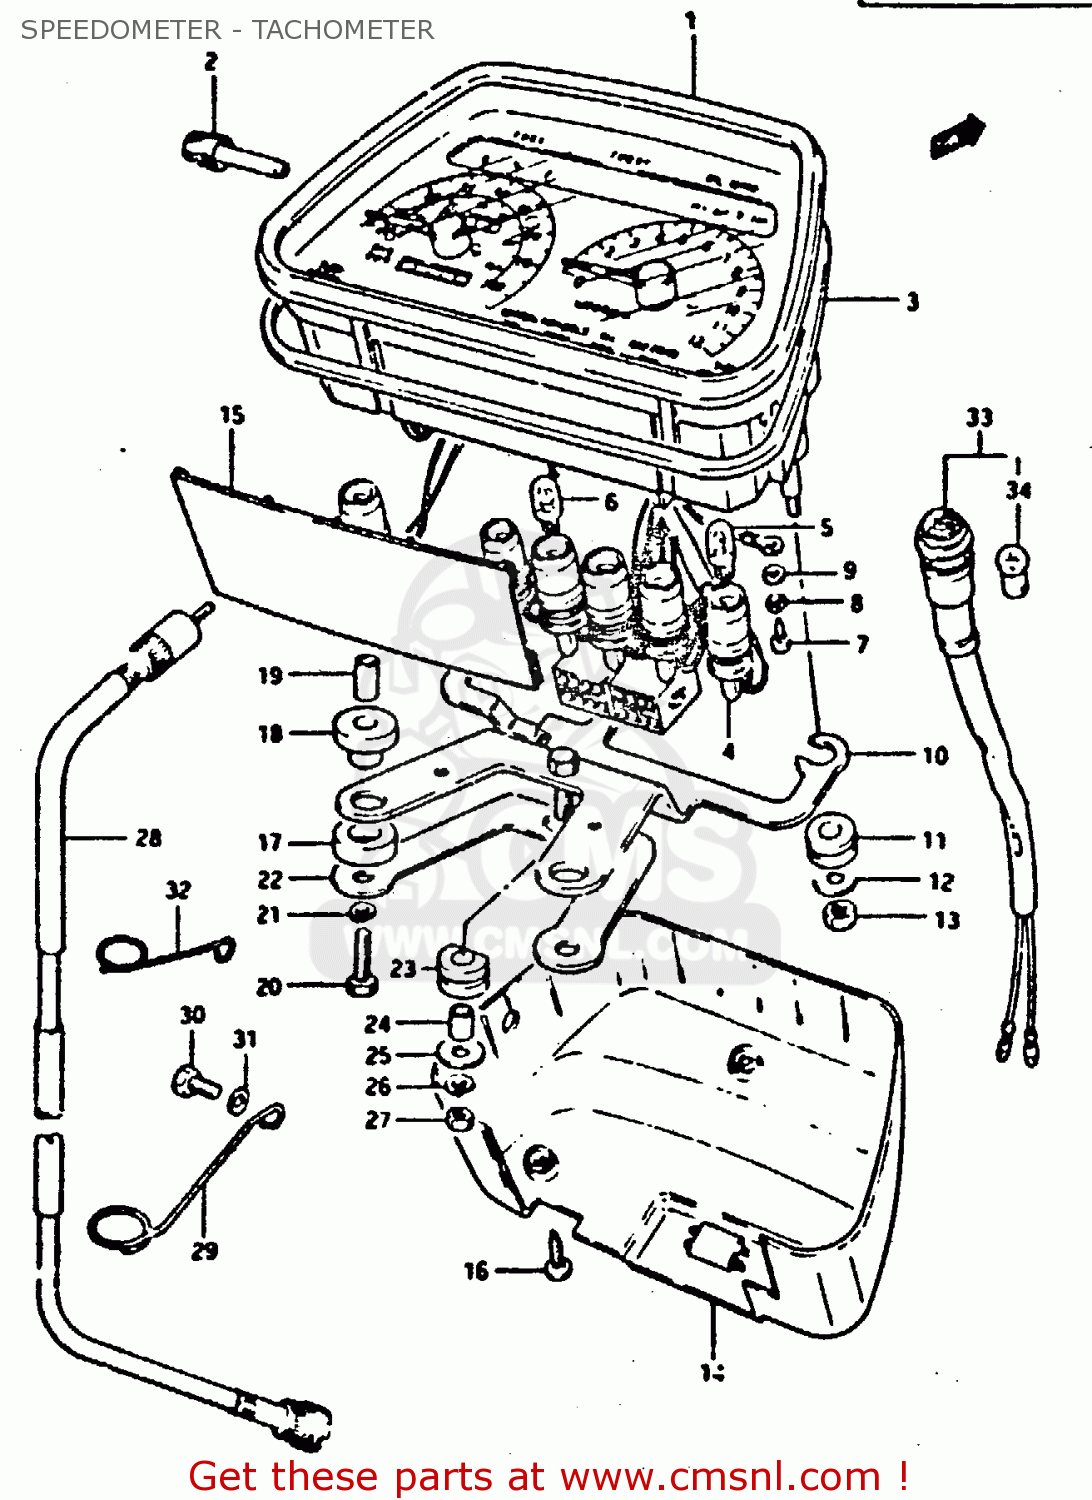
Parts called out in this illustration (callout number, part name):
1	SPEEDO & TACHOMETER (KILO)
2	KNOB,TRIP METER
3	CUSHION,METER
4	SOCKET
5	BULB(12V3.4W,T10)
6	BULB(12V1.7W,T10,WB121)
7	SCREW 3X12
8	LOCK WASHER
9	WASHER
10	BRACKET,METER
11	CUSHION,METER
12	WASHER,METER
13	NUT
14	COVER,METER,UNDER
15	PLATE
16	SCREW
17	CUSHION,METER BRACKET
18	CUSHION
19	SPACER(6.1X8X14.5)
20	BOLT
21	LOCK WASHER
22	BRACKET,METER
23	CUSHION,METER
24	SPACER (6.1X8X15.5)
25	WASHER(6.5X18X1.5)
26	LOCK WASHER
27	NUT
28	CABLE ASSEMBLY,SPEEDOMETER
29	CLAMP,SPEEDOMETER CABLE
30	BOLT, UPPER
31	WASHER
32	GUIDE,SPEEDOMETER CABLE UPR
33	LAMP ASSEMBLY,IDLE SWITCH
34	BULB(12V3.4W,STANLEY,A72A)
